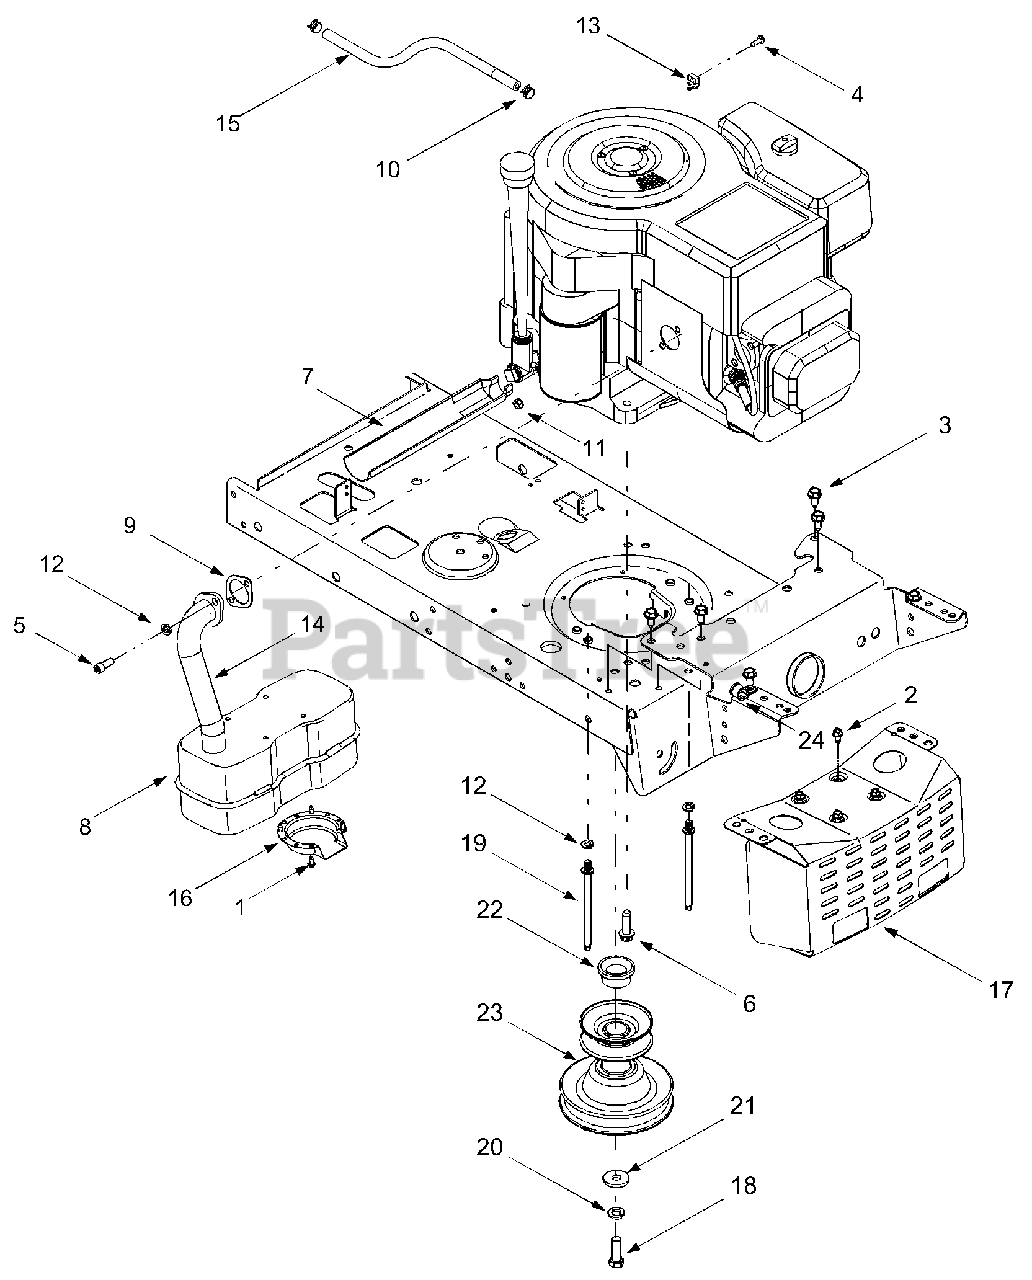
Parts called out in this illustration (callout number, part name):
1	Screw, #8-32 x .375
2	Self-tapping Screw, 1/4-20 x .5
3	Self-tapping Screw, 5/16-12 x .75
4	Screw, #10-32 x .625
5	Socket Cap Screw, 5/16-18 x .625
6	Self-tapping Screw, 3/8-16 x 1.25
7	Oil Drain Sleeve
8	Muffer, Single Inlet
9	Exhaust Gasket
10	Hose Clamp, .490
11	Hex Sems Nut, 1/4-20
12	Lock Washer, 5/16
13	Casing Clamp
14	Exhaust Pipe
15	Fuel Line Hose
16	Muffler Deflector
18	Hex Screw, 7/16-20 x 1.25
19	Belt Keeper Pin, 5/16 x 4.75
20	Lock Washer, 7/16
21	Flat Washer, .450 x 1.25 x .164
22	Spacer, 1.0 x 1.4 x .825
23	Engine Pulley, 3.56 x 5.56
24	Clamp
